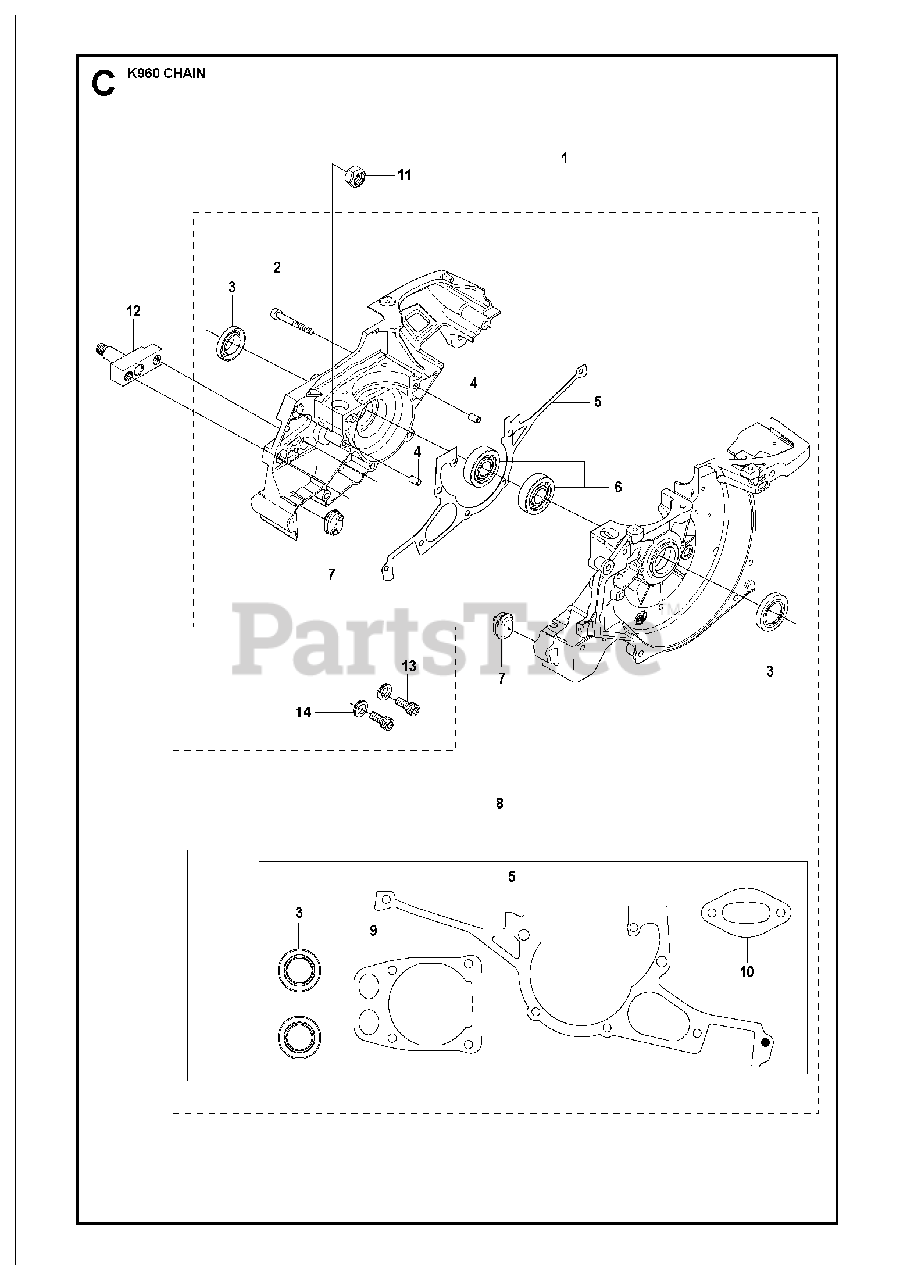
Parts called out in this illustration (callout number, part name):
1	CRANKCASE ASSYIncl. 2 - 8
2	SCREW ITXSCM
3	SEALING RINGGasket kit 8
4	GUIDE BUSHING
5	GASKETGasket kit 8
6	BALL BEARING
7	RUBBER BUSHING
8	GASKET KITIncl. 3, 5, 9, 10
9	GASKET
10	GASKET
